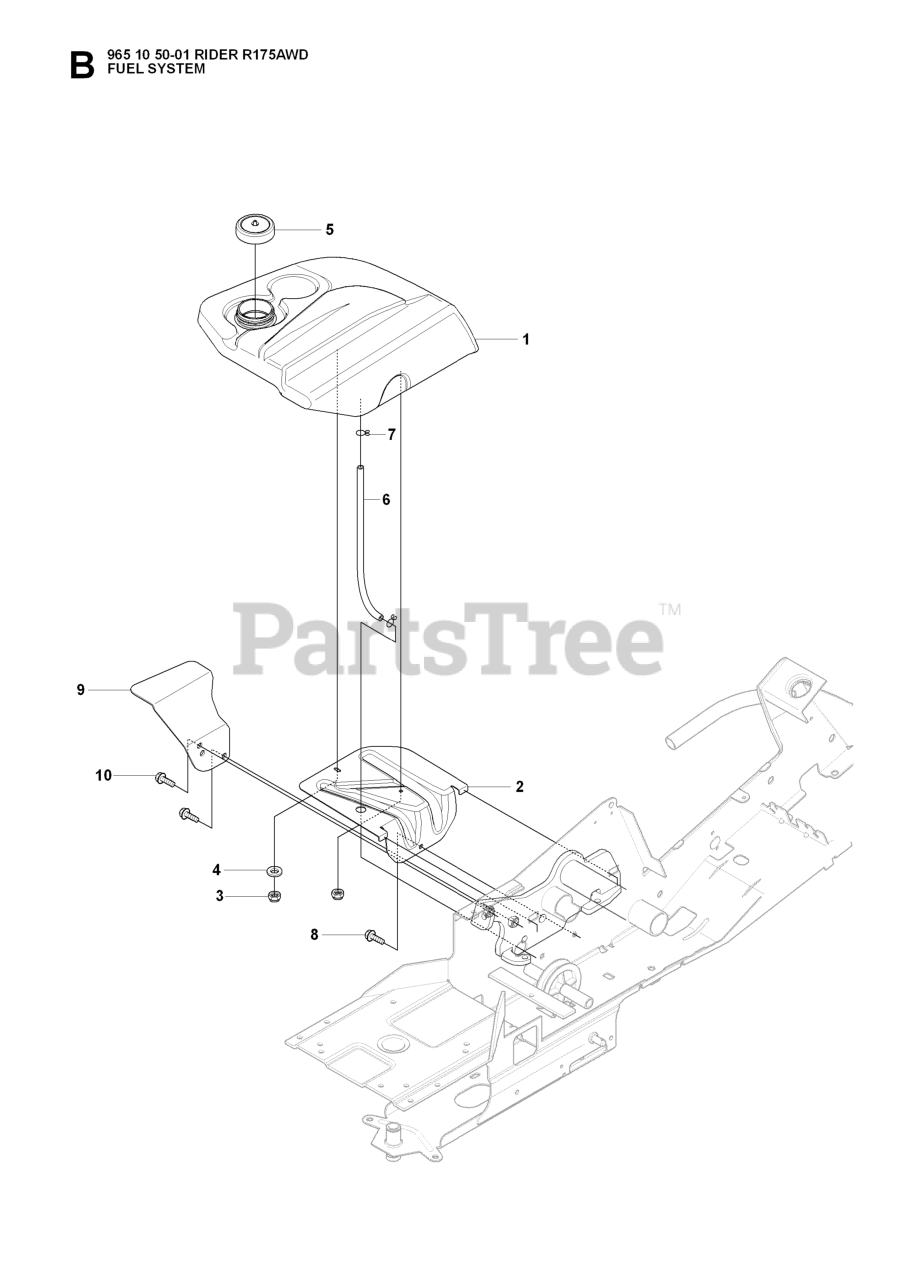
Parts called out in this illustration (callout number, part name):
3	LOCKNUT M6
4	WASHER
10	Screw M10x25
